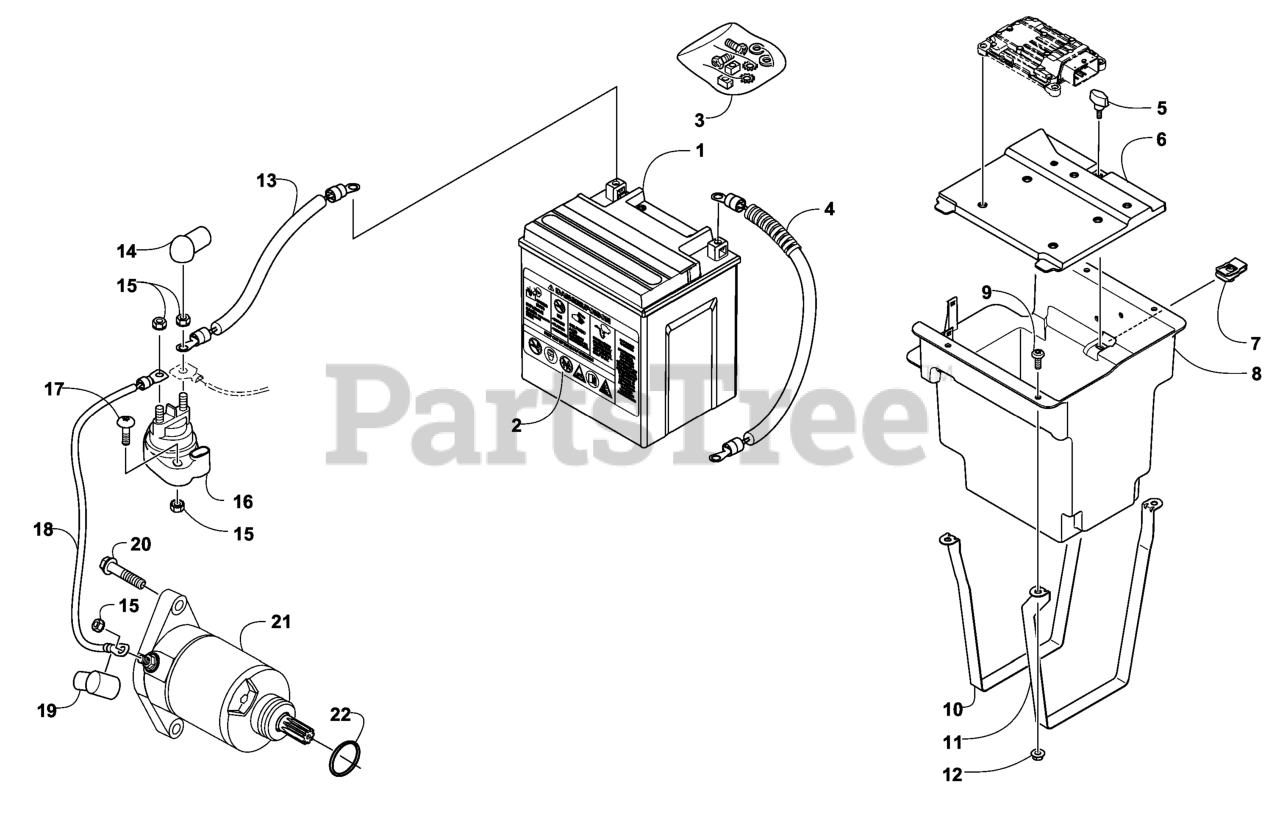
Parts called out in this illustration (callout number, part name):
1	BATTERY-AGM-30AH WET
2	LABEL-POISON/DANGER
3	HARDWARE-BATTERY PACK
4	CABLE-BATTERY
5	KNOB-PLASTIC
6	COVER-BATTERY
7	CLIP-U NUT
8	BOX-BATTERY
9	SCREW-TSPRH
10	GUIDE - BELT, 32
11	STRAP-BATTERY BOX, LH
12	NUT-HHF
13	CABLE-BATTERY, SOLENOID
14	BOOT-TERMINAL, SOLENOID
15	NUT-HH, SEMS
16	SOLENOID-STARTER RELAY
17	SCREW-TSPRH
18	CABLE-SOLENOID, STARTER
19	BOOT-TERMINAL, BATTERY
20	BOLT-FLANGE
21	MOTOR-STARTER
